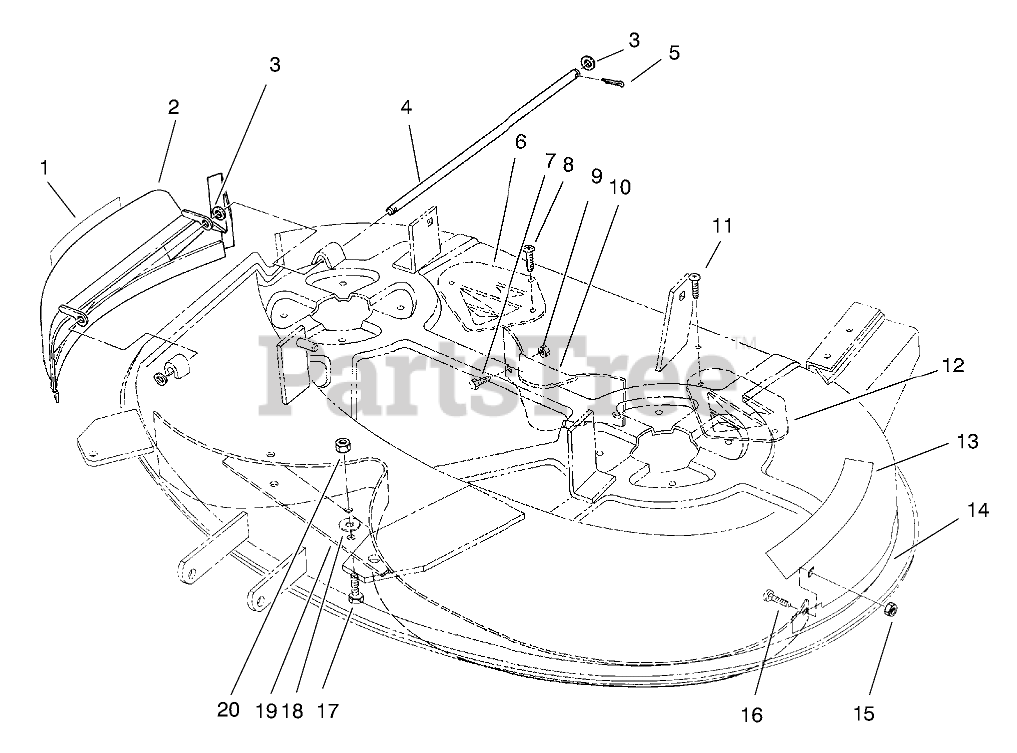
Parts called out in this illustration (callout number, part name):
1	Decal-Danger
2	Recycler Chute Assembly (Incl. Ref.# 1)
3	WASHER-PLAIN
5	PIN-COTTER
6	KICKER
7	SCREW-HH
8	SCREW-PPH, PLASTITE
9	NUT-LOCK, NI
10	Baffle-Rear
11	#8 X .625" PHILPS PAN H
12	PLATE-KICKER
13	DECAL-DANGER
14	DECAL-38" RECYCLER
15	NUT-LOCK, NI
16	BOLT-CARR
17	SCREW-HH
18	WASHER
19	Baffle-38"
20	NUT-LOCK, NI
